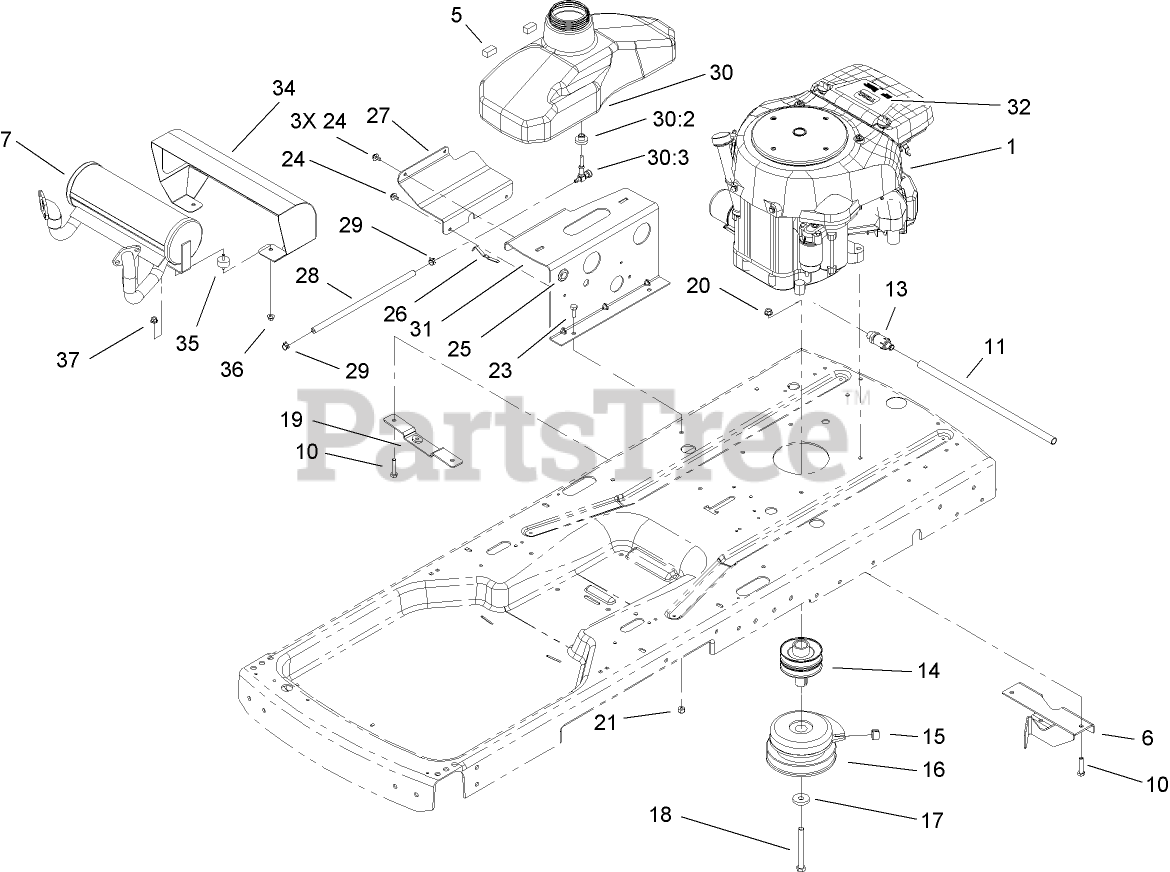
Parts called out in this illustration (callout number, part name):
1	Loose Parts Package
5	FOAM-SWITCH, SEAT
6	BRACKET-PIVOT
7	MUFFLER
10	SCREW-HH
11	TUBE-DRAIN, OIL
13	VALVE-DRAIN, OIL
14	PULLEY-ENGINE
15	BUMPER
16	CLUTCH-ELECTRIC
17	WASHER
18	SCREW-HH
19	PLATE-MOUNT, IDLER
20	NUT-HF
21	NUT-LOCK, NI
23	SCREW-HH
24	SCREW-HHFTF
25	GROMMET
26	SPRING
27	PLATE-SUPPORT
28	HOSE-FUEL
29	CLAMP-HOSE
30	GAS TANK ASM
30:2	BUSHING
30:3	VALVE-FUEL
31	PLATE-TANK
35	ISOLATOR-RUBBER
36	NUT-HHF
37	NUT-HF
